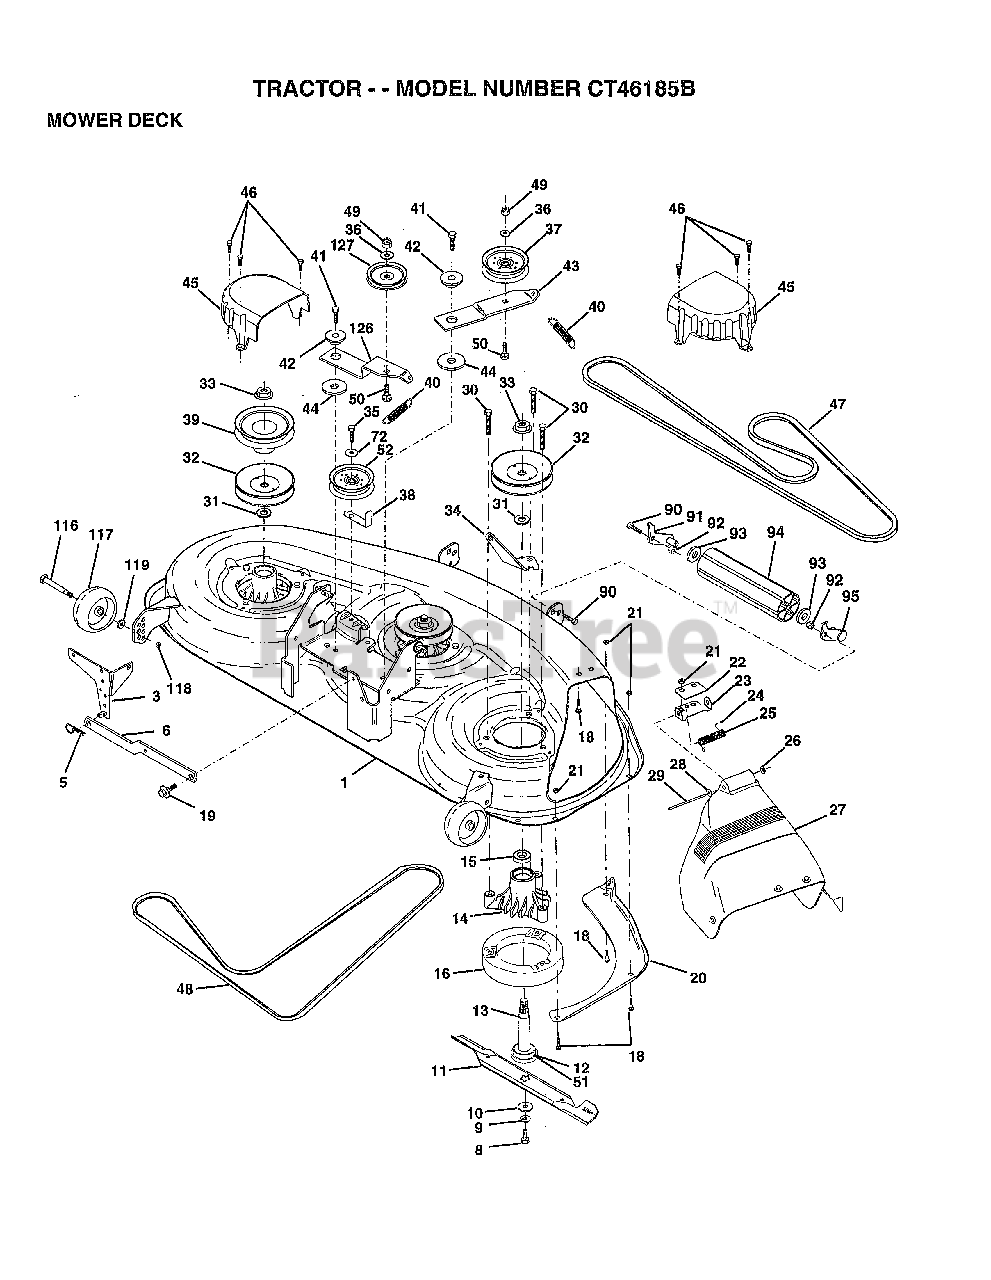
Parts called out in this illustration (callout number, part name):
1	"DECK.ASM.MOWER46"""
3	BRKT.ASM.SW.44/50
8	BLADE BOLT
10	WASHER.HARD.BLADE
11	"BLADE.HIGHLIFT46"""
12	BEARING.BALL
13	SHAFT.ASM.W/BRNG
14	HOUSING.MAND.44.V
15	BEARING
16	STRIPPER RND MWR
18	BOLT
19	BOLT SHD 5/16-18
20	BAFFFLE.VORTEX.46
22	STIFFENER BRKT
23	DEFLECTOR BRKT
24	CAP-SLEEVE LT
26	NUT PUSH M
27	SHIELD DEFLECTOR
28	WASHER
29	HINGE ROD
30	"SCREW-THD ROLL,WA"
31	WASHER
32	PULLEY.MAND.36/46
34	ANCHOR.SPRING.46
35	SCREW LT
36	WASHER
37	FLAT IDLER PULLEY
38	"KEEPER BELT,IDLER"
39	PULLEY.DRV.DCK.46
40	"SPRING.SEC.44""VEN"
41	SCREW
42	SPACER RETAINER
43	ARM.IDLER.DECK.46
44	HARDENED WASHER
45	COVER.MANDREL.46
46	SCREW.1/4-20X5/8
47	BELT-V.SEC.46.KEL
48	BELT V PRIM 50
50	BOLT.3/8-16X1.50
51	WASHER.FELT.
52	"PULLEY IDLER,FLAT"
72	WASHER HYT
90	BOLT
92	NUT
93	WASHER
116	BOLT.SHOULDER
117	WHEEL.GUAGE.MED.
118	LOCKNUT
119	WASHER
126	ARM.IDLER.PRIM.46
127	PULLEY.IDLER.4.25
